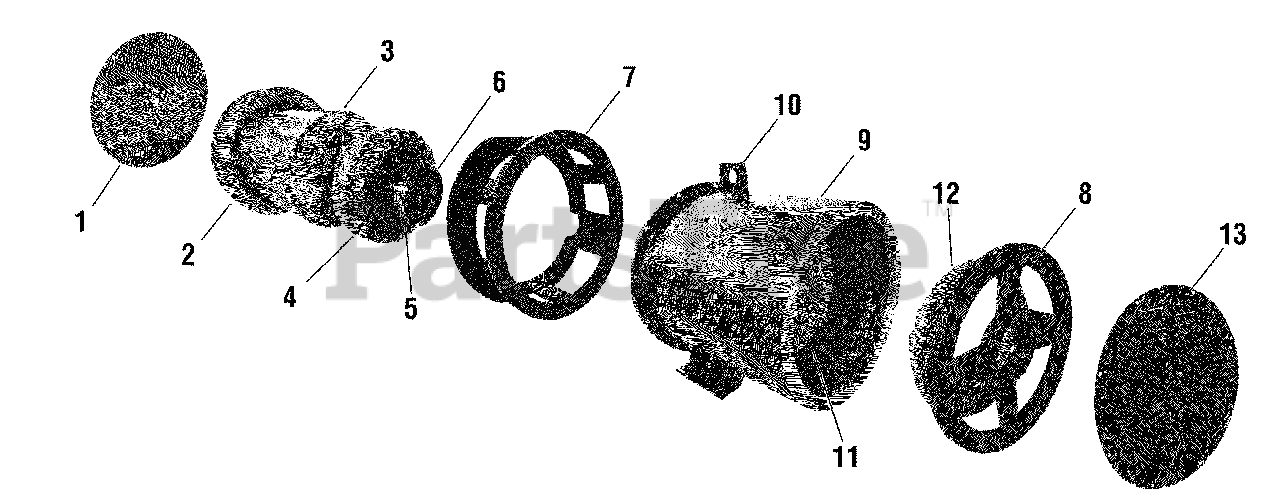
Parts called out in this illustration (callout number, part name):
1	DISC, Coupling
2	FAN
3	ROTOR
5	RECTIFIER ASSEMBLY RING
7	HOUSING, Bell
8	BEARING SUPPORT
9	HOUSING, Generator
10	LIFTING EYE
11	STATOR
12	EXCITER, Stator
13	COVER
